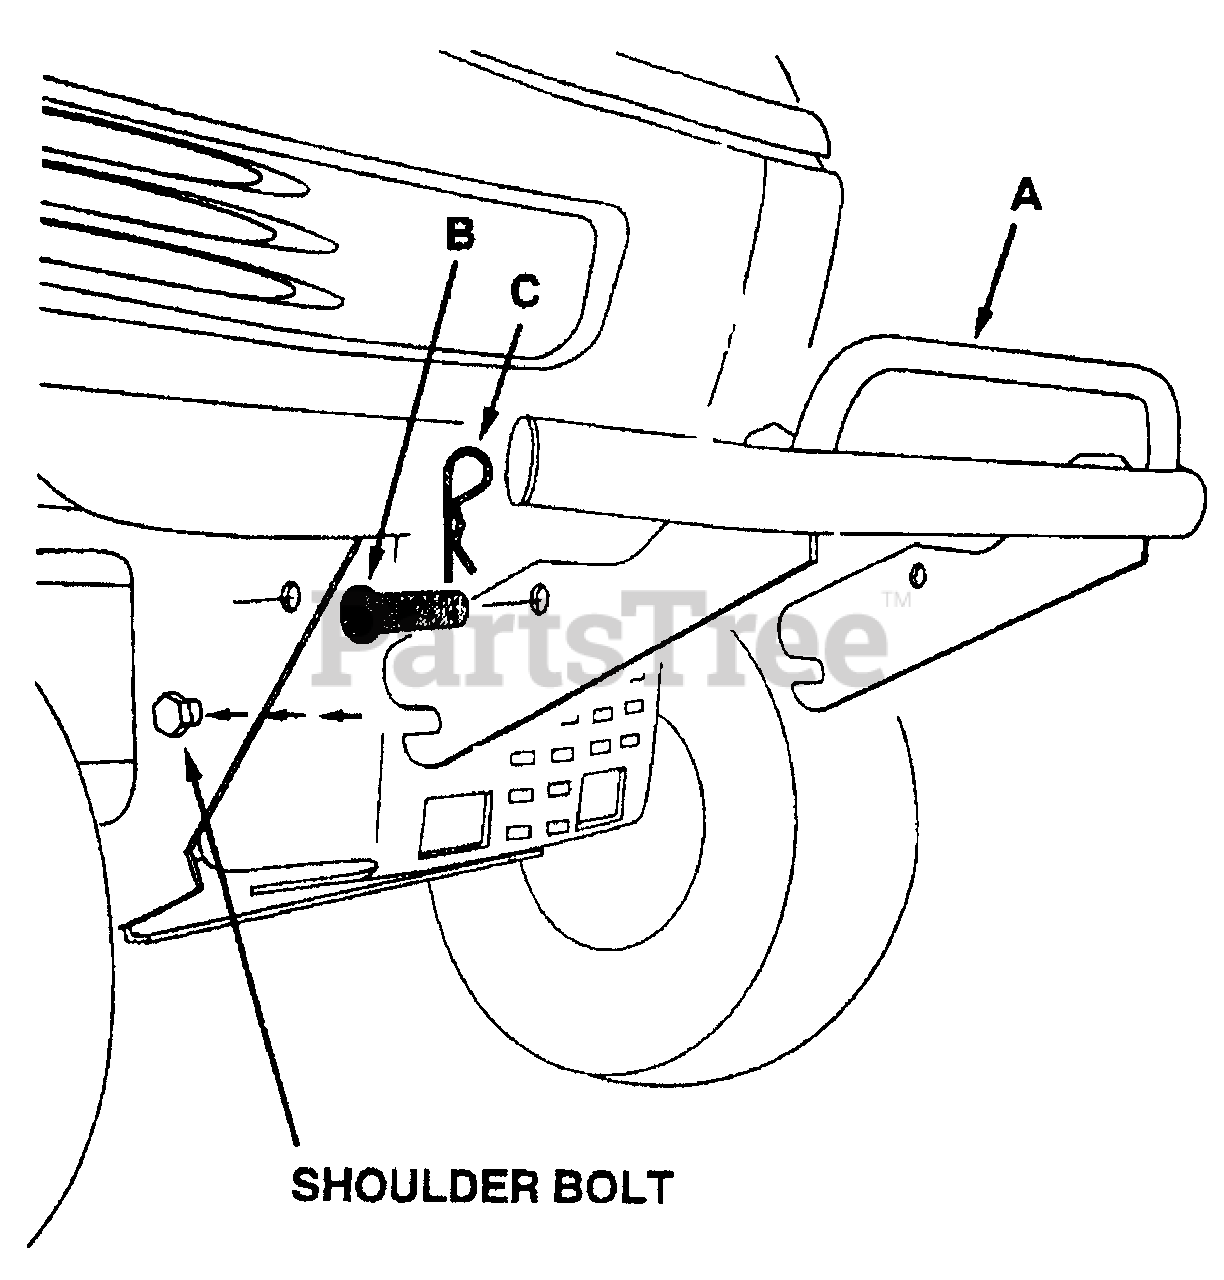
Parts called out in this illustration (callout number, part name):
A	Bumper Assembly
B	Clevis Pin, 1/2" x 1"
C	Hair Cotter Pin, 3/32"
